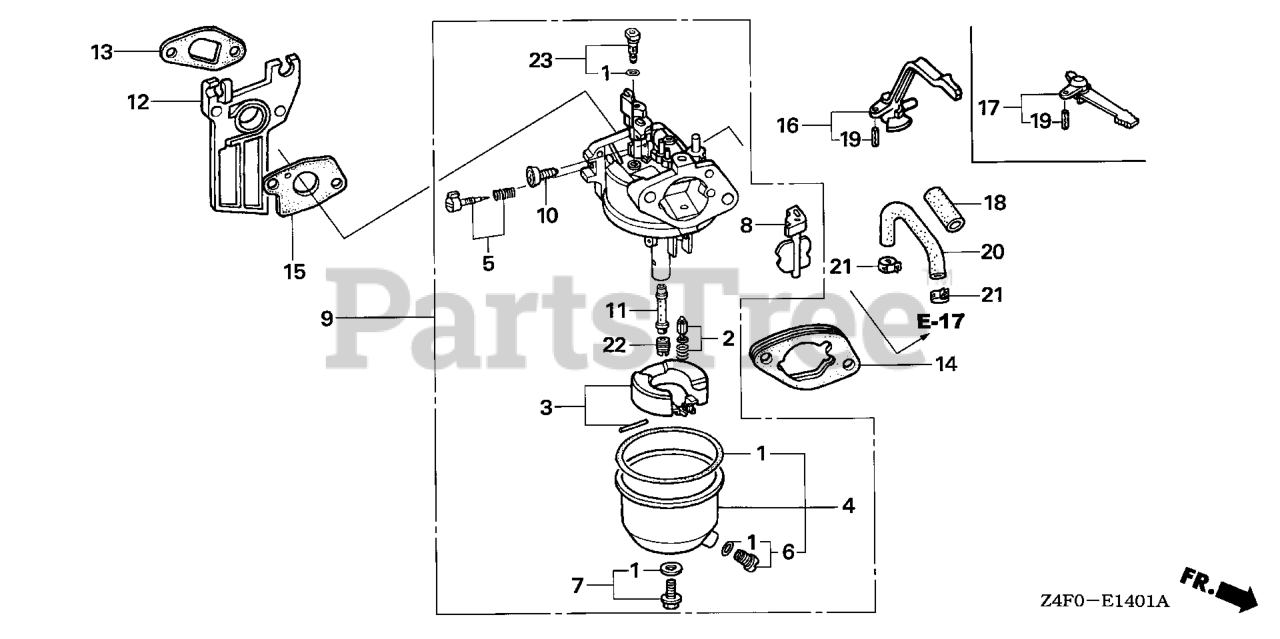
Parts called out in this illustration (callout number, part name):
1	GASKET SET (CARBURETOR NO.)
2	VALVE SET, FLOAT (CARBURETOR NO.) (SEAT NOT INCLUDED)
3	FLOAT SET
4	CHAMBER SET, FLOAT (CARBURETOR NO.)
4	CHAMBER SET, FLOAT (CARBURETOR NO.) (FOR BE12A A)
5	SCREW SET (Honda Code 4219879). (CARBURETOR NO.)
6	SCREW SET, DRAIN (Honda Code 1672187). (CARBURETOR NO.)
7	SCREW SET B
7	SCREW SET
8	CHOKE SET
9	CARBURETOR ASSY. (BE62C A)
10	SCREW, THROTTLE STOP
11	NOZZLE, MAIN
12	INSULATOR, CARBURETOR
13	GASKET, INSULATOR
14	SPACER, CARBURETOR
15	GASKET, CARBURETOR
17	LEVER, CHOKE (STD)
18	RUBBER, SUPPORTER (107MM)
19	PIN, SPRING (2X12)
20	TUBE, FUEL (4.5X400) (FKM)
20	BULK HOSE, FUEL (4.5X8000) (95001-450(95001-45001-60M)
21	CLIP, TUBE (D8)
22	JET, MAIN (#58) Use from Engine SN BE30B E.
22	JET, MAIN (#60)
22	JET, MAIN (#62)
23	JET SET, PILOT (#35)
